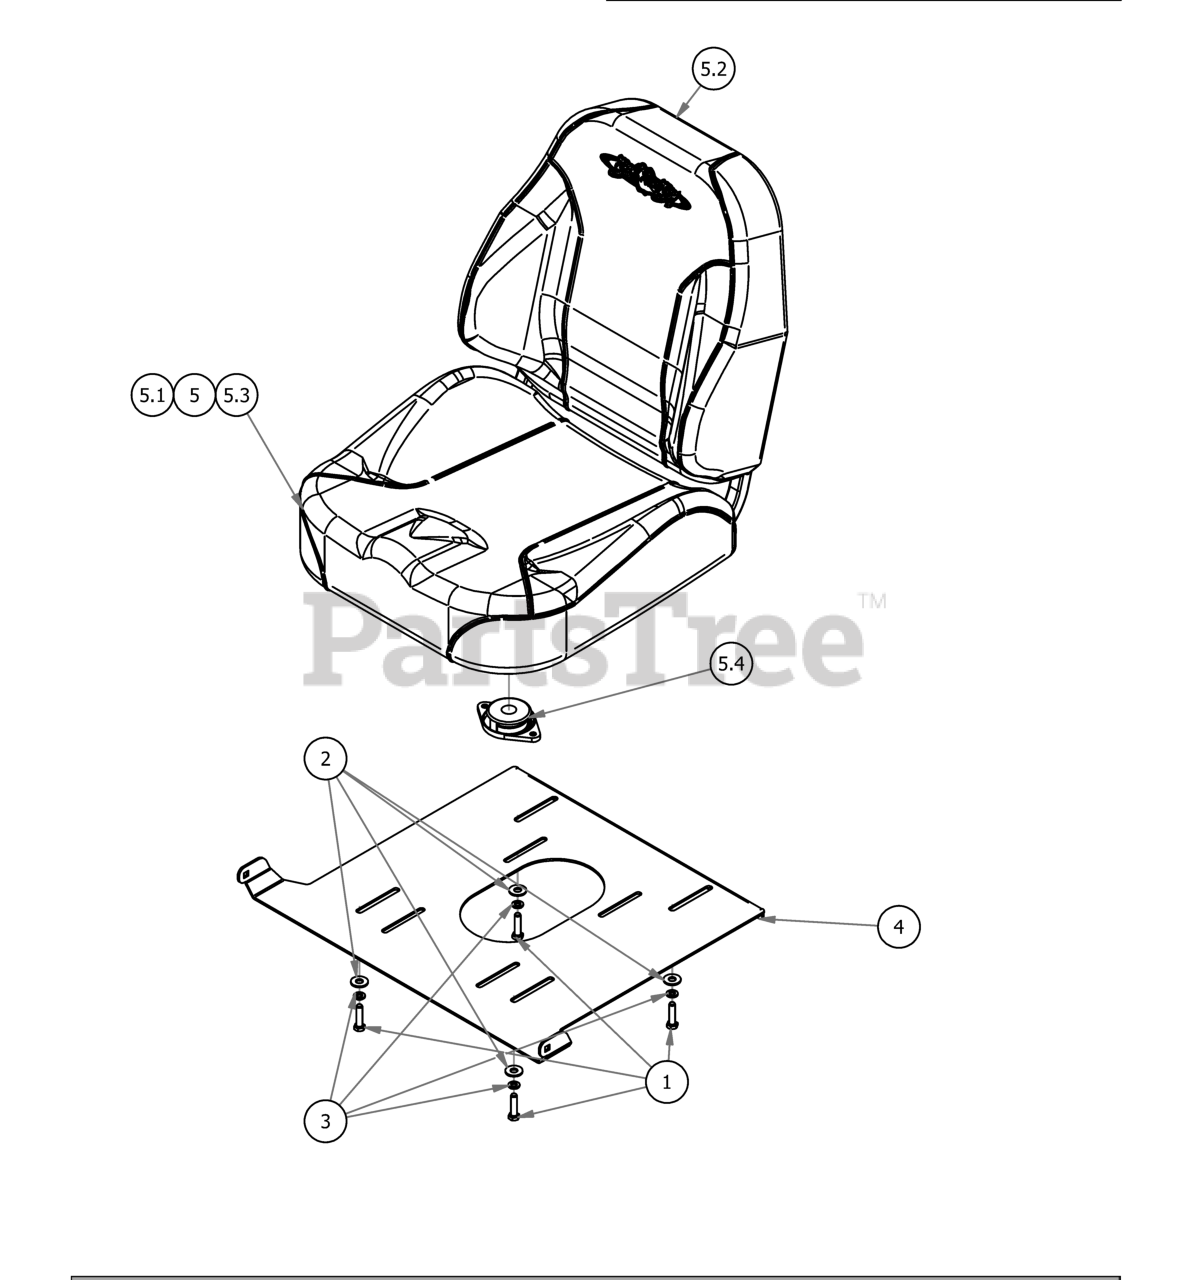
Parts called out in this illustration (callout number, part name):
1	5/16-18 X 1-1/4 HEX C/S (GR.5) ZC
2	5/16 USS FLAT WASHER (7/8 OD) ZINC
3	5/16 SPLIT LOCKWASHER ZINC
4	2017 MZ Seat Plate
5	2020 ZT AVENGER SEAT
5.1	FOAM MOLDED SEAT
5.2	Seat Back Cushion
5.3	Seat Bottom Cushion
5.4	Seat Safety Switch
